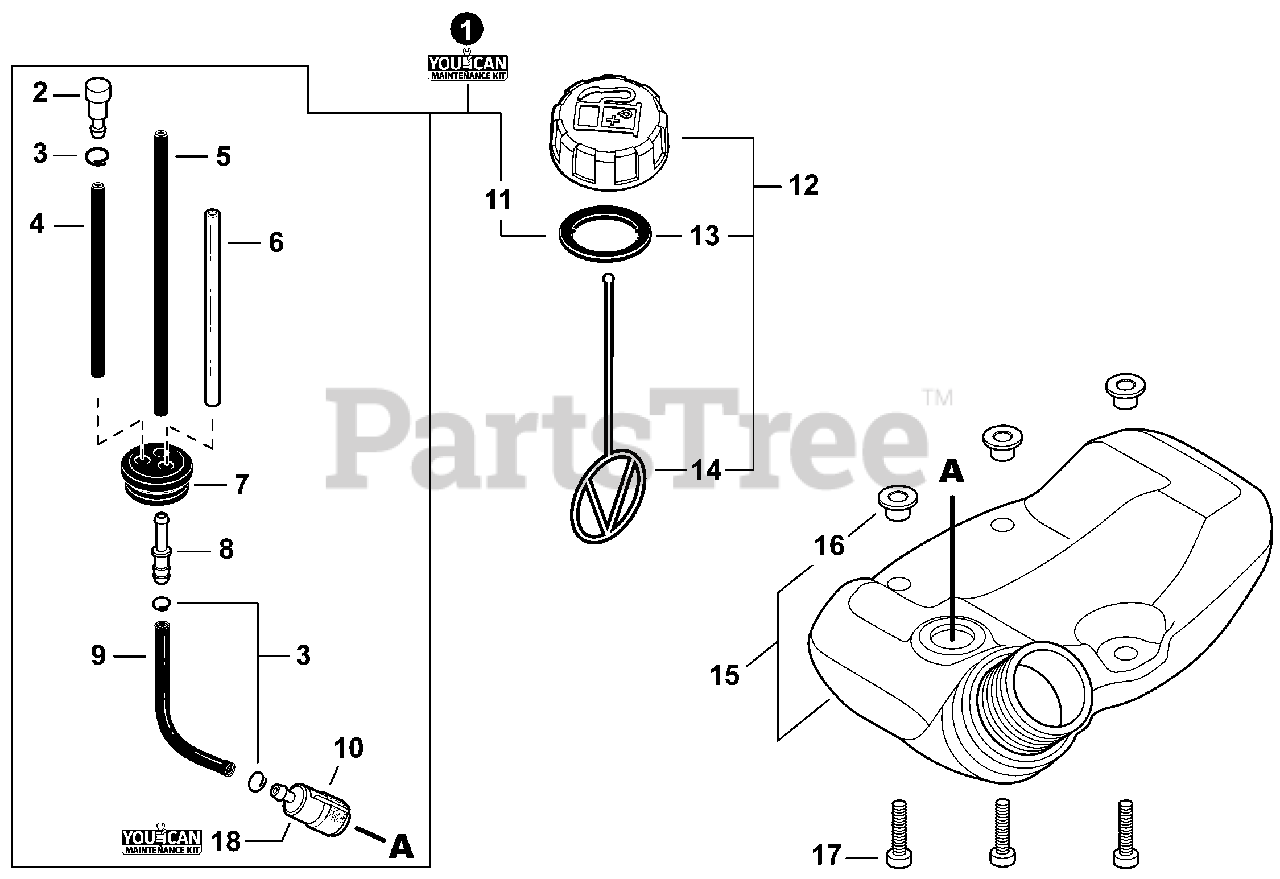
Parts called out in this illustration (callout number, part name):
1	FUEL SYSTEM KIT - YOUCAN™
2	VENT ASSY
3	CLIP Ø6
4	PIPE, FUEL 3×5×90 BLACK
5	PIPE, FUEL 3×5×74 BLACK
6	PIPE, FUEL 3×6×80 CLEAR
7	GROMMET, FUEL Ø5
8	CONNECTOR, PIPE Ø5ר3.5
9	PIPE, FUEL 3×5×130 BLACK
10	FILTER, FUEL
11	GASKET, FUEL CAP
12	CAP ASSY, FUEL
13	GASKET, FUEL CAP
14	CONNECTOR, CAP L= 123
15	TANK ASSY, FUEL
16	COLLAR 5
17	BOLT, TORX 5×20
18	TUNE-UP KIT - YOUCAN™
